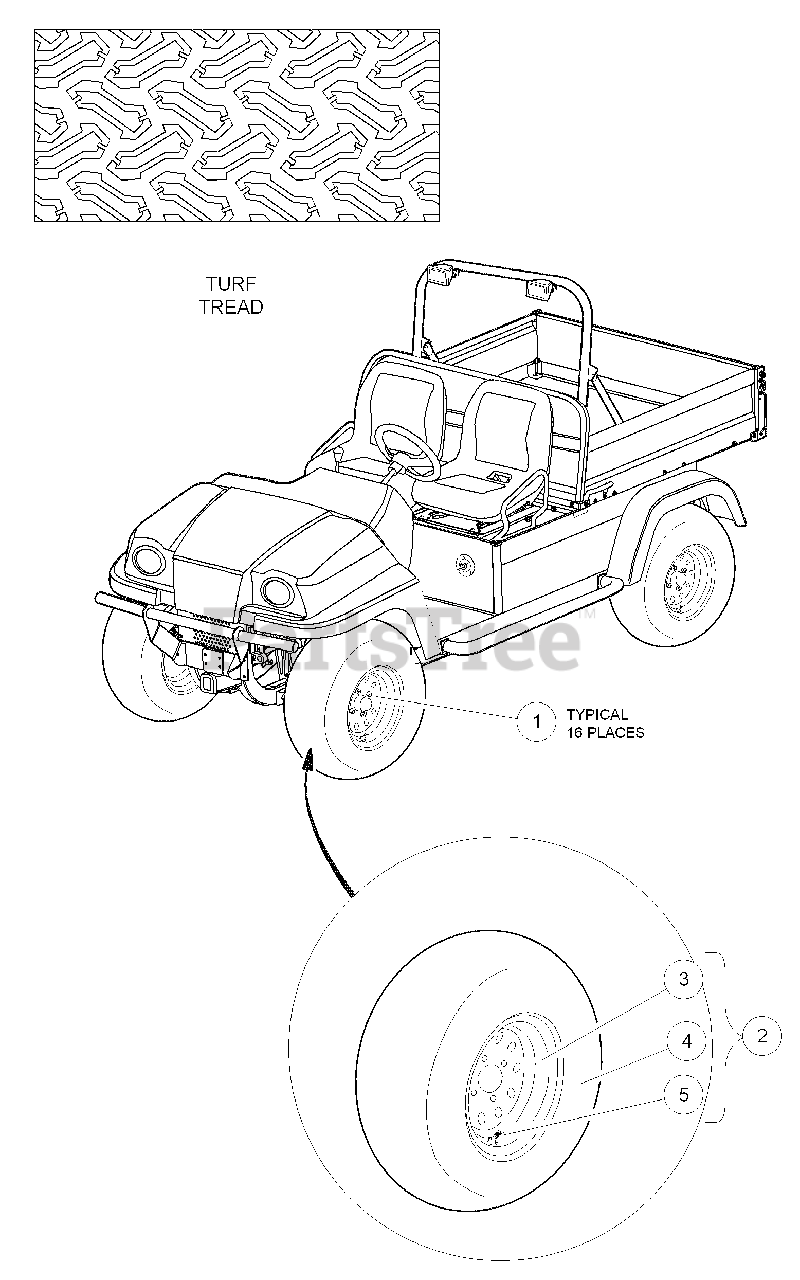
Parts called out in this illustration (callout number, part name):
1	.500-20 Unf Lug Nut
2	Gray Tire Assembly, Turf Tread
3	Wheel Rim, Gray
4	Tire, Turf
